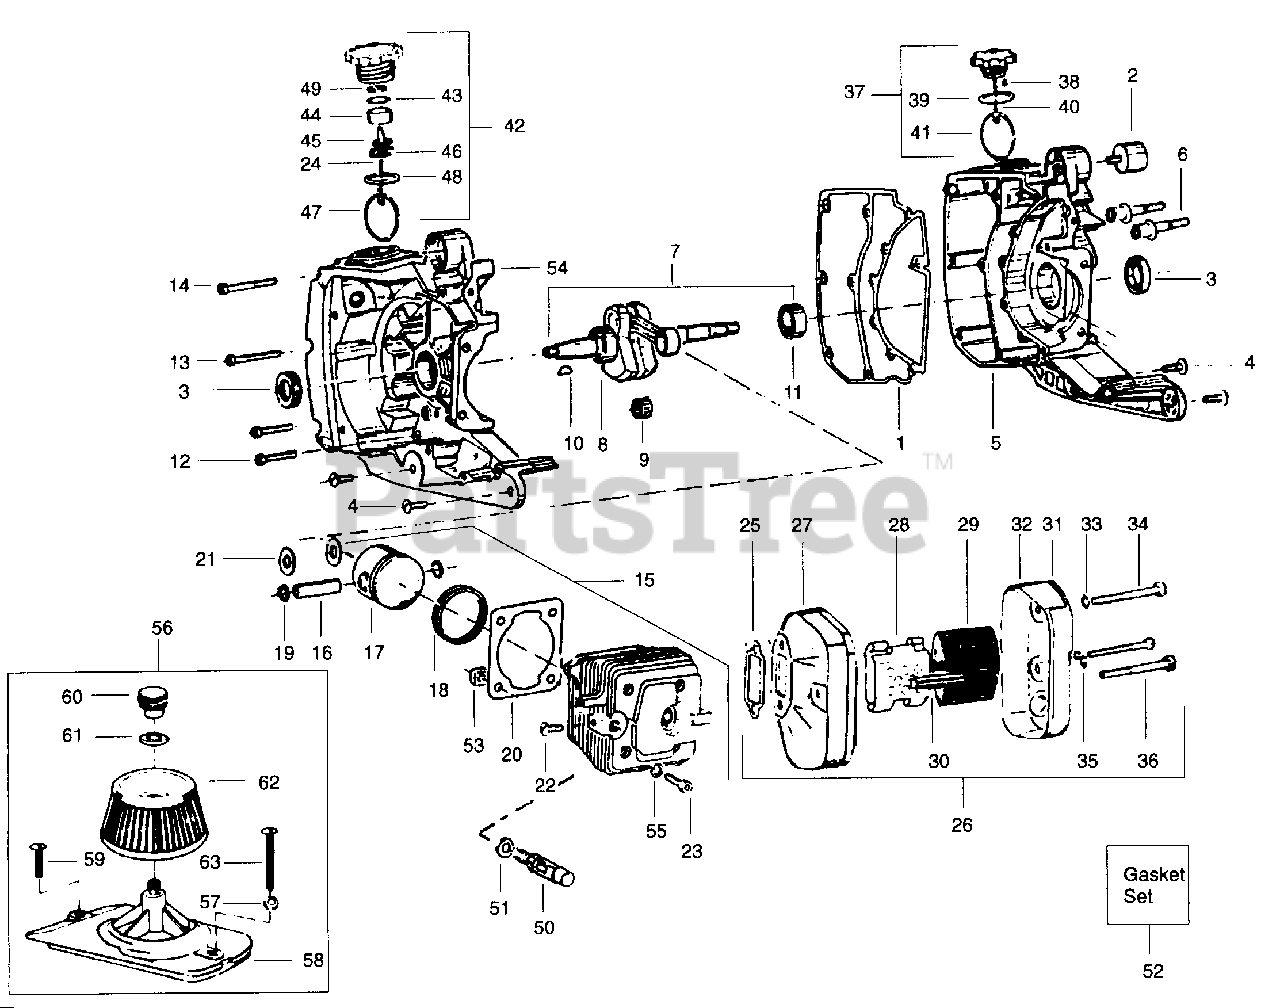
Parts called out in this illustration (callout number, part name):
1	Crankcase Gasket
2	Shock Absorber
5	C'Case & Stud Ass,y. (Incl. 6)
6	Bar Mounting Studs
7	Crankshaft Ass'y. (incl. 8-11)
8	Main Bearing
10	Flywheel Key
15	Cylinder & Piston Kit (Incl. 9, 20, 17)
18	Piston Ring Set
20	Cylinder Gasket
21	Thrust Washer
22	Plate Screw
24	Bead Chain
25	Muffler Gasket
27	Muffler Body
28	Muffler Channel
29	Muffler Screen
31	Muffler Cover
32	Heat Shield Ass'y.
33	Lockwasher
35	Lockwasher
37	Oil Cap Ass'y.
40	Bead Chain
41	Retainer
42	Gas Cap Ass'y.
45	Umbrella Valve
46	Gas Cap Cover
47	Retainer
50	Decompression Valve
52	Gasket Set
54	C'Case Half M/S
56	Air Filter Kit-Optional
58	Filter Base Ass'y.
62	Filter Element
